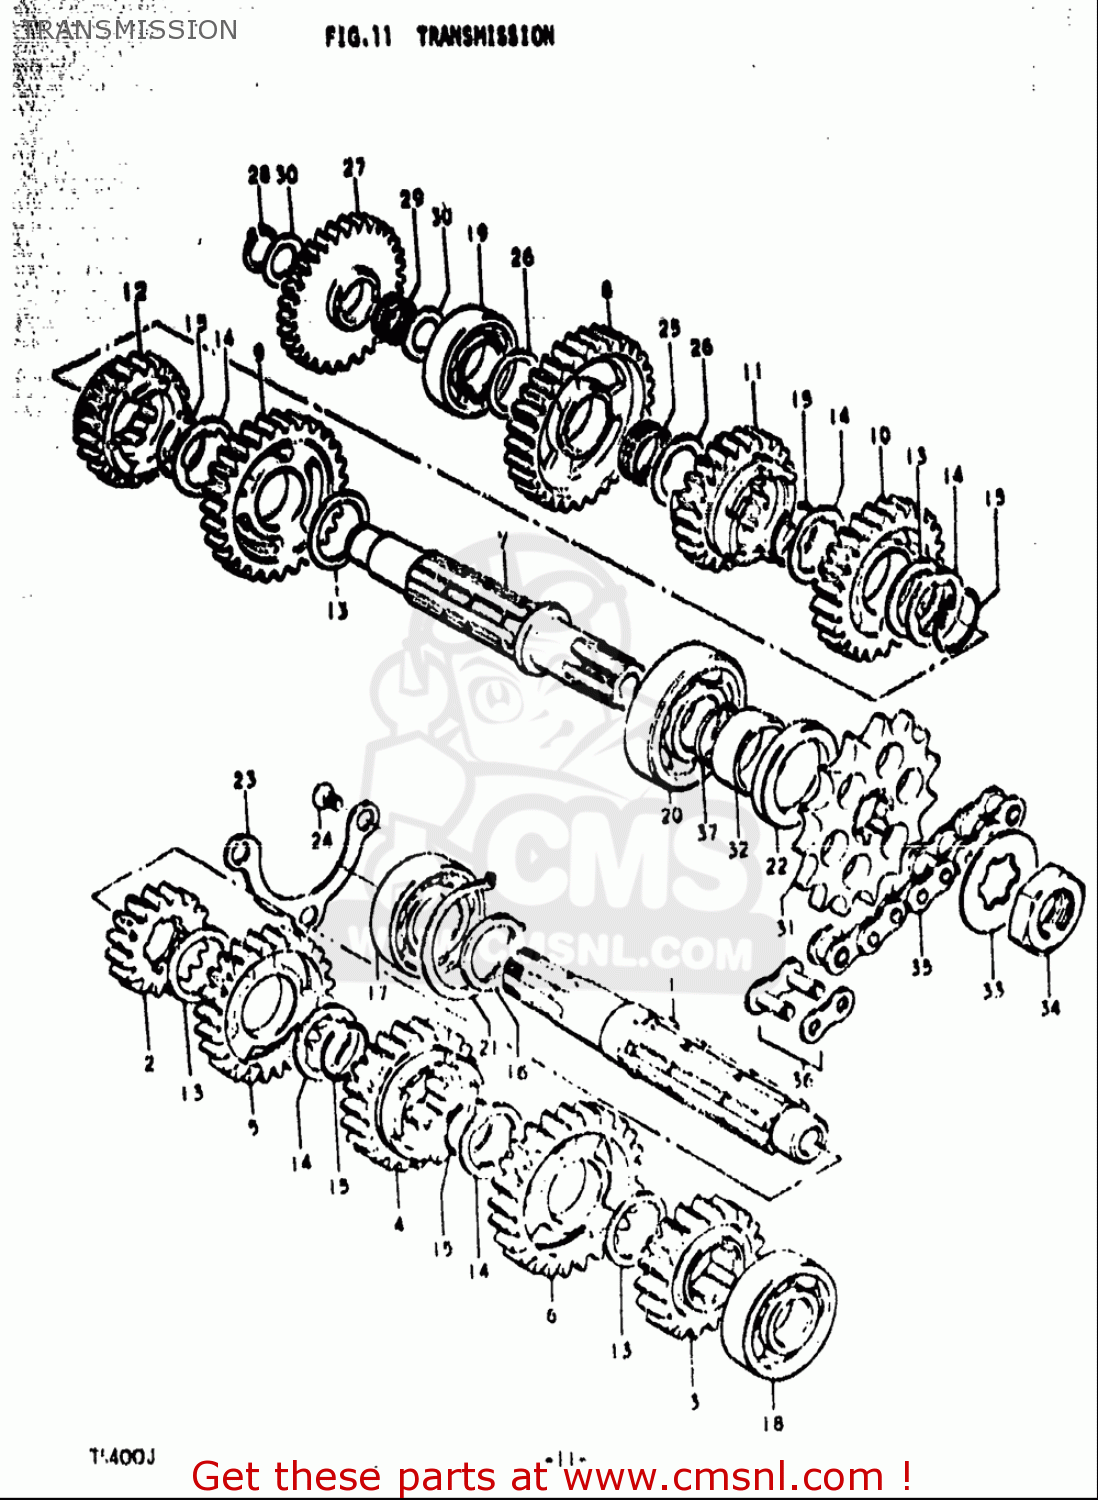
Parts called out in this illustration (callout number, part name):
13	WASHER
14	WASHER,LOCK
15	RING,SNAP
17	BEARING
18	BEARING(20X47X14)
20	BEARING(22X56X16)
24	SCREW
26	WASHER (20X30X1)
28	CIRCLIP
29	BEARING(17X21X9.8)
30	WASHER
31	SPROCKET,ENGINE
33	WASHER,LOCK
34	NUT
35	CHAIN,DRIVE #525TR-10
36	JOINT ASSEMBLY,CHAIN
37	O RING(D:1.7,ID:22)
